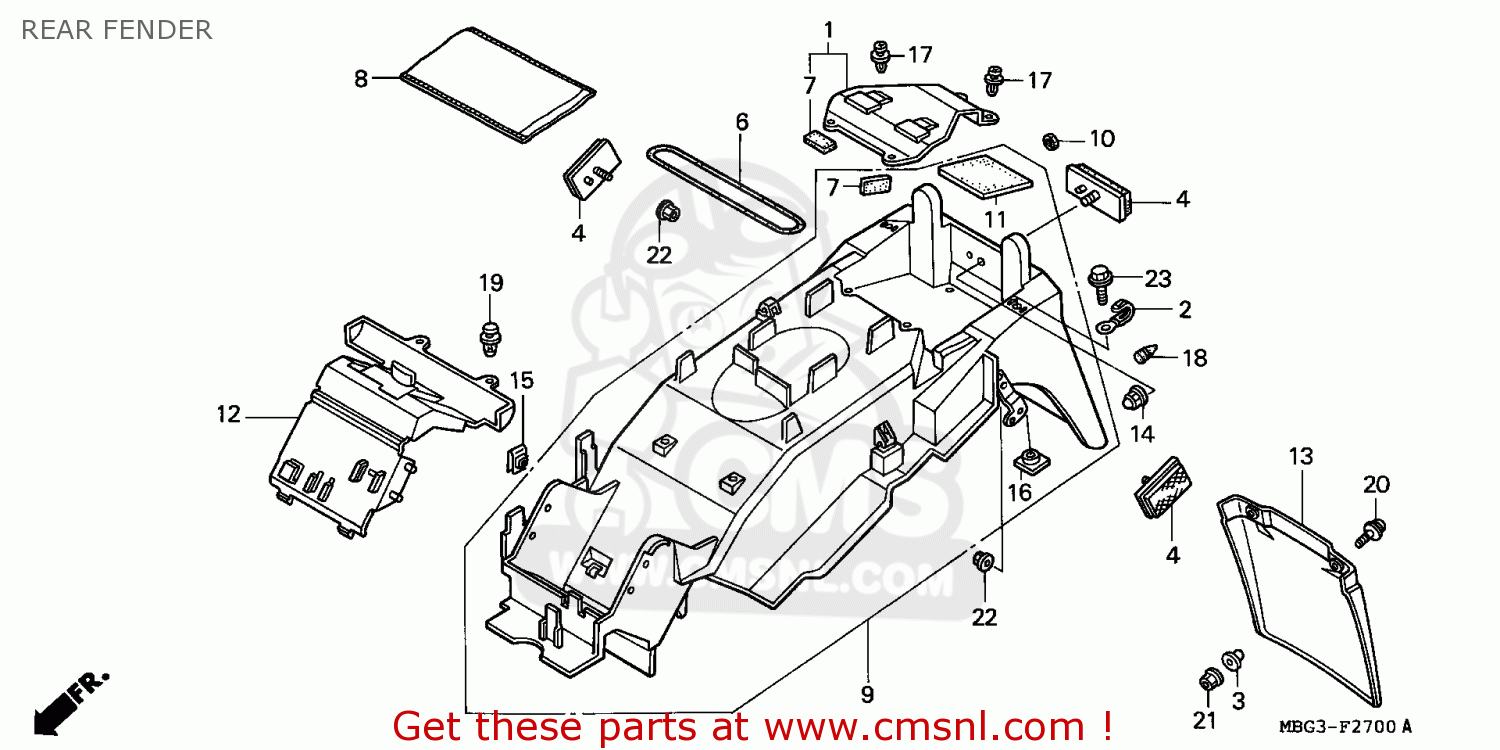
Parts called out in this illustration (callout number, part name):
1	COVER,FI UNIT .
2	CLIP,PULSER CORD.
4	REFLECTOR,REFLEX
6	BAND,U LOCK
7	RUBBER,BATTERY
8	BAG,SERVICE BOOK
9	FENDER,RR
10	RUBBER,CUSHION
11	MAT,FI.UNIT
12	COVER,BATTERY TRA
14	NUT,FLG CAP,5MM
15	NUT,CLIP 6MM
16	NUT 6MM SPL
17	CLIP,TRIM
19	CLIP,PANEL F*NH1*
23	BOLT,FLANG,6X16
